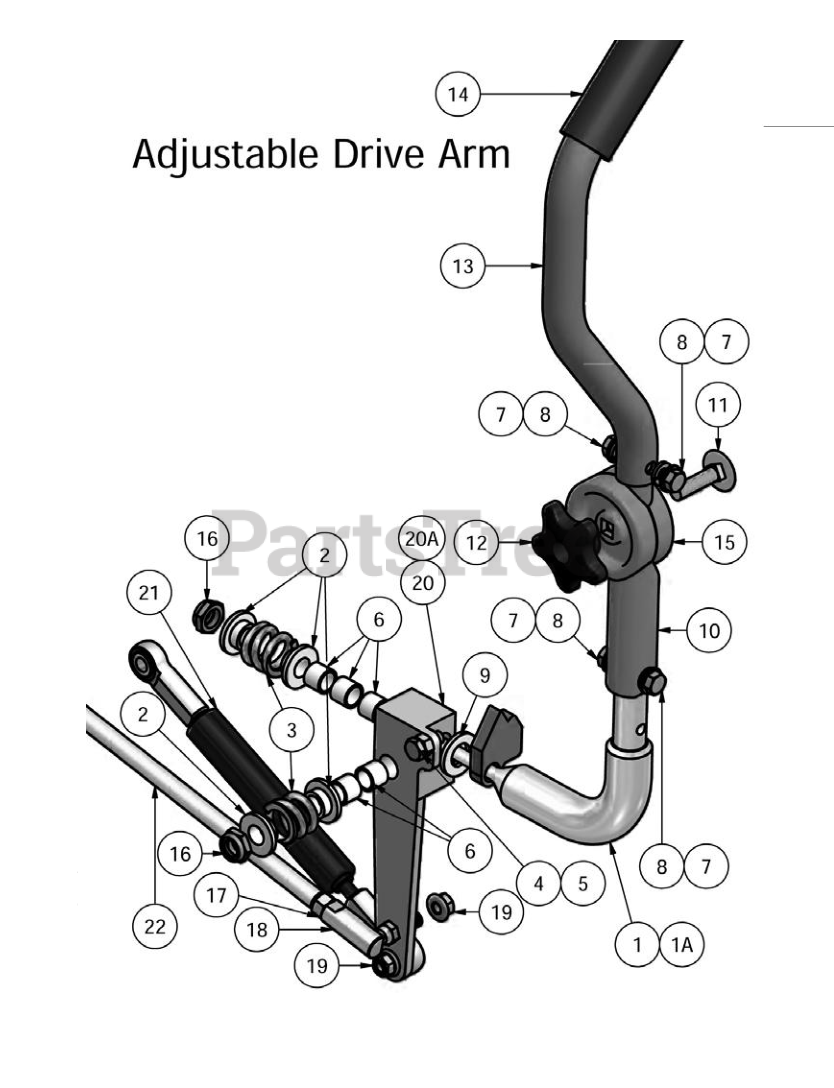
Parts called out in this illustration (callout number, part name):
1	Steering Arm Base-Right
1A	Steering Arm Base-Left
2	.515 ID Nylon Shoulder Washer
3	Drive Lever Spring
4	5/16" x 3/4" Hex Bolt
6	.507 ID Nylon Bushing
7	5/16" Lock Washer
8	5/16" x 1/2" Flange Bolt
9	.635 ID Plastic Washer
10	Upper Adjuster for Steering Arm
11	3/8" x 1-1/4" Carriage Bolt
12	Black Knob for Adjustable Steering Arm
13	Upper Steering Arm Tubing-Adjustable
14	Rubber Grip
15	Lower Adjuster for Steering Arm
16	1/2" Nylcock Nut (1/2 Jam)
17	3/8" Fine Threaded Jam Nut
18	3/8-24 Ball joint (female/male)
19	5/16" Flange Nut
20	Drive Arm Lever Housing (Right)
20A	Drive Arm Lever Housing (Left)
22	Push Rod for Compact Diesel
